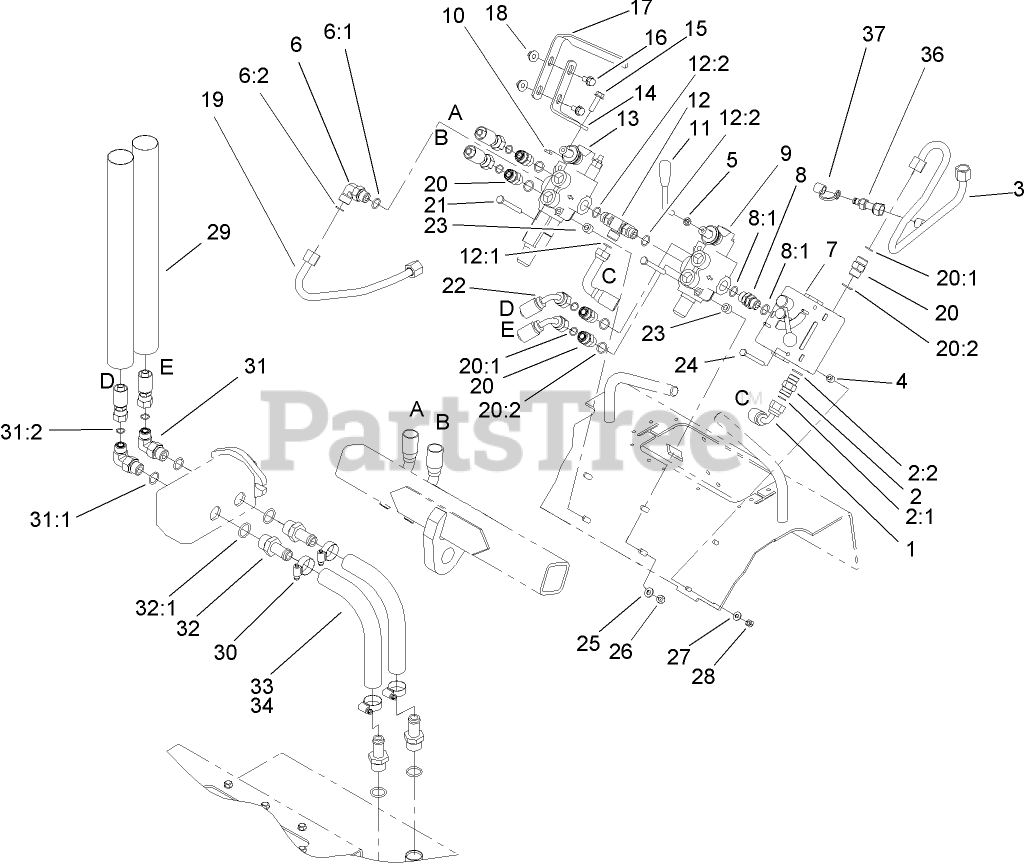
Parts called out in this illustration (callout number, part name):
1	HOSE ASM
2	VALVE-CHECK, HYD
2:1	O-RING
2:2	O-RING
3	TUBE-HYD
4	SPACER
5	NUT-HEX
6	FITTING-ELBOW-90 DEG
6:1	O-RING
6:2	O-RING
7	HYD VALVE KIT
8	FITTING-THREAD, STRAIGHT
8:1	O-RING
9	VALVE-SELECTOR, HYD
10	NUT-HEX
11	LEVER-VALVE
12	ADAPTER-TEE, ADJUSTABLE
12:1	O-RING
12:2	O-RING
13	VALVE-HYD, AUXILIARY
14	MOUNT-CONTROL
15	SCREW-HHF
16	SCREW-HHF
17	GRIP-CONTROL
19	TUBE-HYD
20	FITTING-STRAIGHT
20:1	O-RING
20:2	O-RING
21	SCREW-HH
22	HOSE-HYD
23	SPACER
24	SCREW-HH
25	WASHER-PLAIN
26	NUT-LOCK, NI
27	WASHER-FLAT
28	NUT-LOCK, NI
29	SLEEVE-GUARD, HOSE
30	CLAMP-HOSE
31	FITTING-ELBOW 90
31:1	O-RING
31:2	O-RING
32	FITTING-STRAIGHT
32:1	O-RING
33	HOSE-SUCTION, HYD
36	NIPPLE-TEST
37	CAP-DUST
